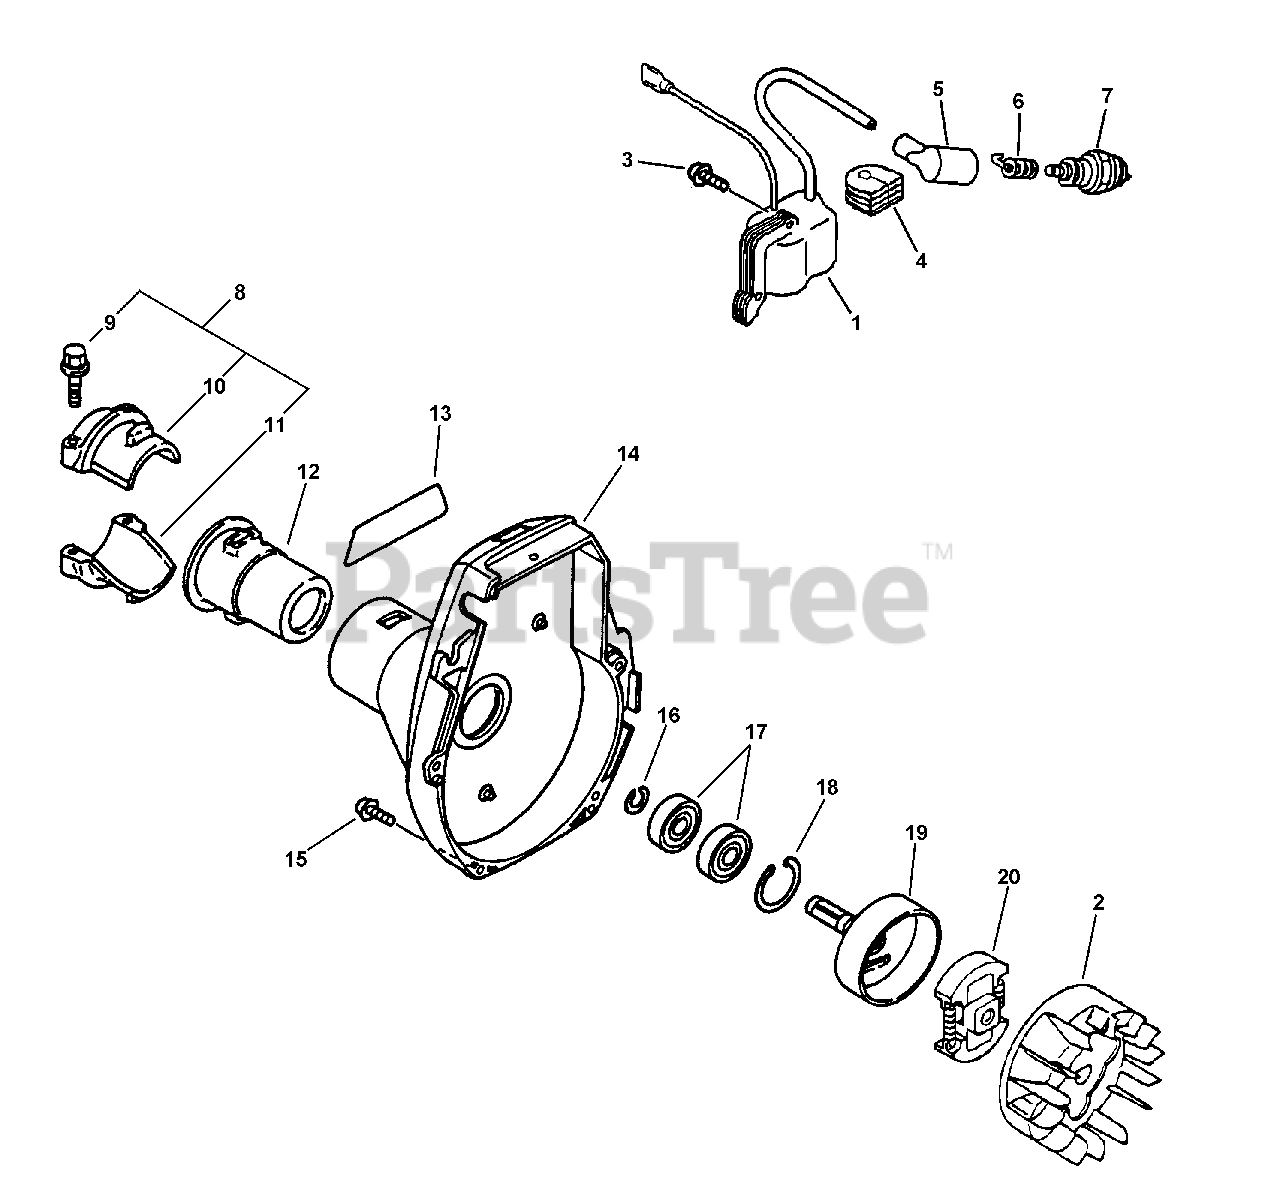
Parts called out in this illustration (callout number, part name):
1	Coil, Ignition
2	Flywheel
3	Screw 4x22
5	Cap, Spark Plug
6	Coil, Spark Plug Cap
7	Plug, Spark BPM-7A
8	Holder Kit
9	Bolt 5x25
10	Holder - Upper
11	Holder - Lower
13	Label, Model SRM-2100
13	Label, Model SRM-2110
14	Fan Cover Asy
15	Screw 4x16
16	Circlip 12
17	Bearing, Ball 6001
18	Circlip 28
19	Drum, Clutch
20	Clutch Asy
